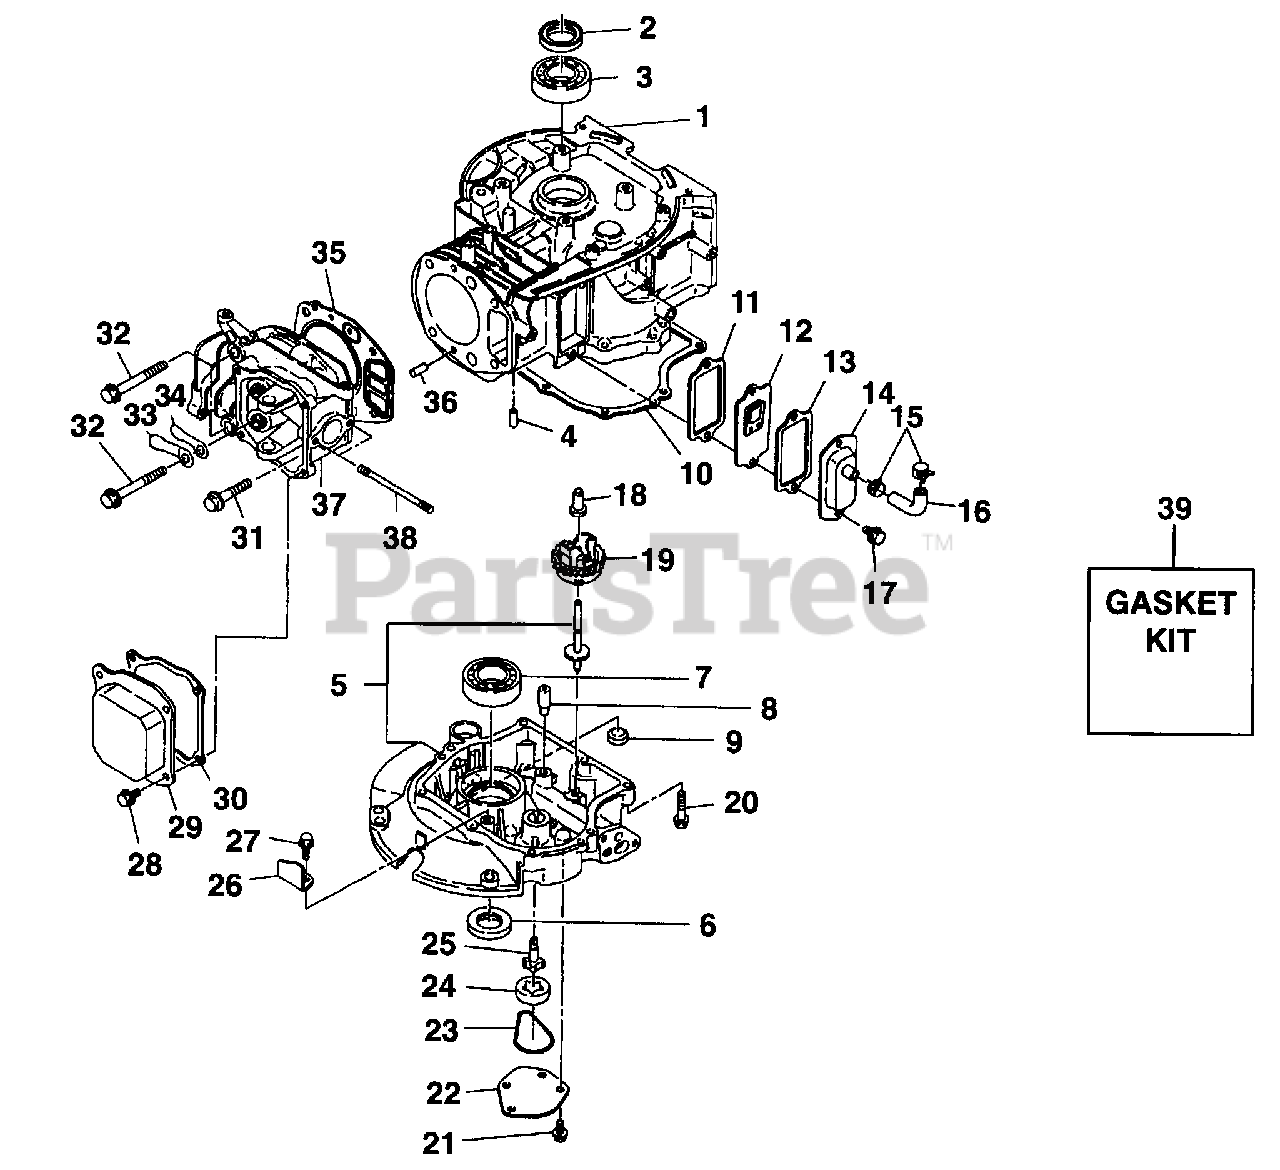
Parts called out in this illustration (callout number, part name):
1	CRANKCASE
2	SEAL, Oil
3	BEARING, Ball
4	PIN, Dowel
5	MAIN BEARING COVER
6	SEAL, Oil
7	BEARING, BALL
10	GASKET, Bearing Cover
11	GASKET, Breather Plate
12	BREATHER PLATE
13	GASKET, Tappet Cover
14	TAPPET COVER
15	CLAMP, Hose
16	RUBBER PIPE
17	BOLT, Flange
18	SLEEVE, Governor
19	GOVERNOR GEAR
20	BOLT & WASHER
21	BOLT, Flange
22	COVER, Oil Pump
24	OIL PUMP, Outer
25	OIL PUMP, Inner
26	PLATE, Oil Shelter
27	BOLT, Flange
28	BOLT, Flange
29	COVER, Rocker
30	GASKET, Rocker Cover
31	BOLT, Flange
32	BOLT, Flange
33	PLATE, Retainer
34	VALVE, Leaf
35	GASKET, Head
36	PIN, Dowel
37	CYLINDER HEAD
39	GASKET SET
